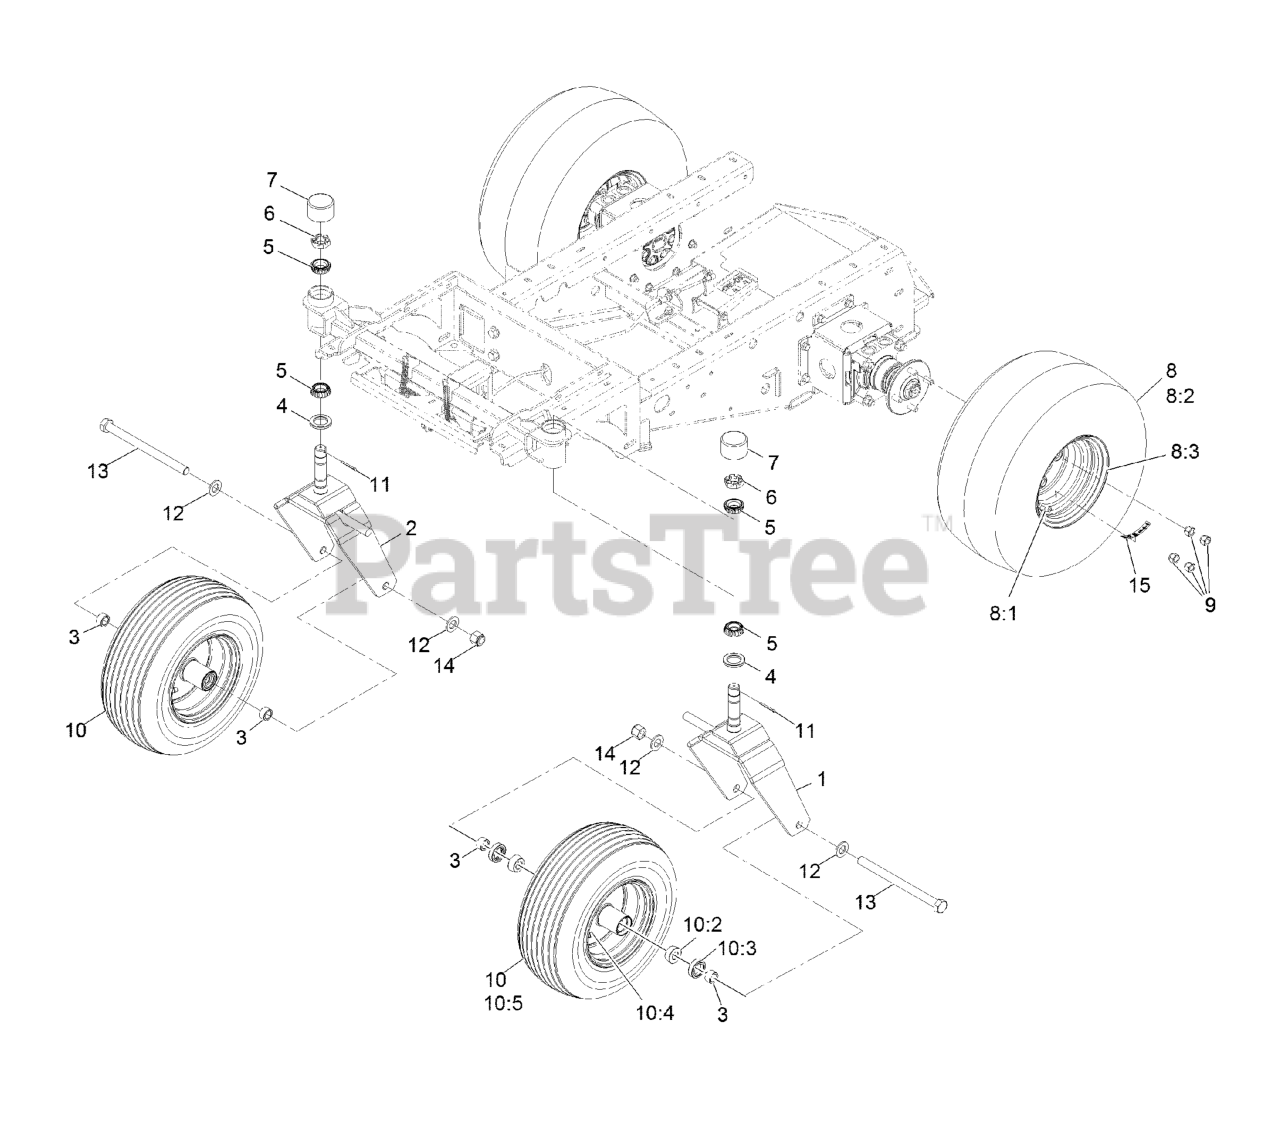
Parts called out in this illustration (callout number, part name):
1	Caster-Lt [black]
2	Caster-Rt [black]
3	SPACER-AXLE
4	SEAL-GREASE
5	CONE-BEARING, OUTER
6	NUT-SHH
7	CAP-DUST, RUBBER
8	WHEEL AND TIRE ASM
8:1	Rim-8 X 7, Black
8:3	Stem-Valve
9	NUT-LUG
10	WHEEL AND TIRE
10:2	BEARING-CONE, TAPERED ROLLER
10:3	SEAL-CASTER
10:4	VALVE
10:5	Tire-Rib
11	Pin-Cotter
12	WASHER-FLAT
13	SCREW-HH
14	NUT-LOCK, NI
15	DECAL-TORQUE, WHEEL HUB LUG
